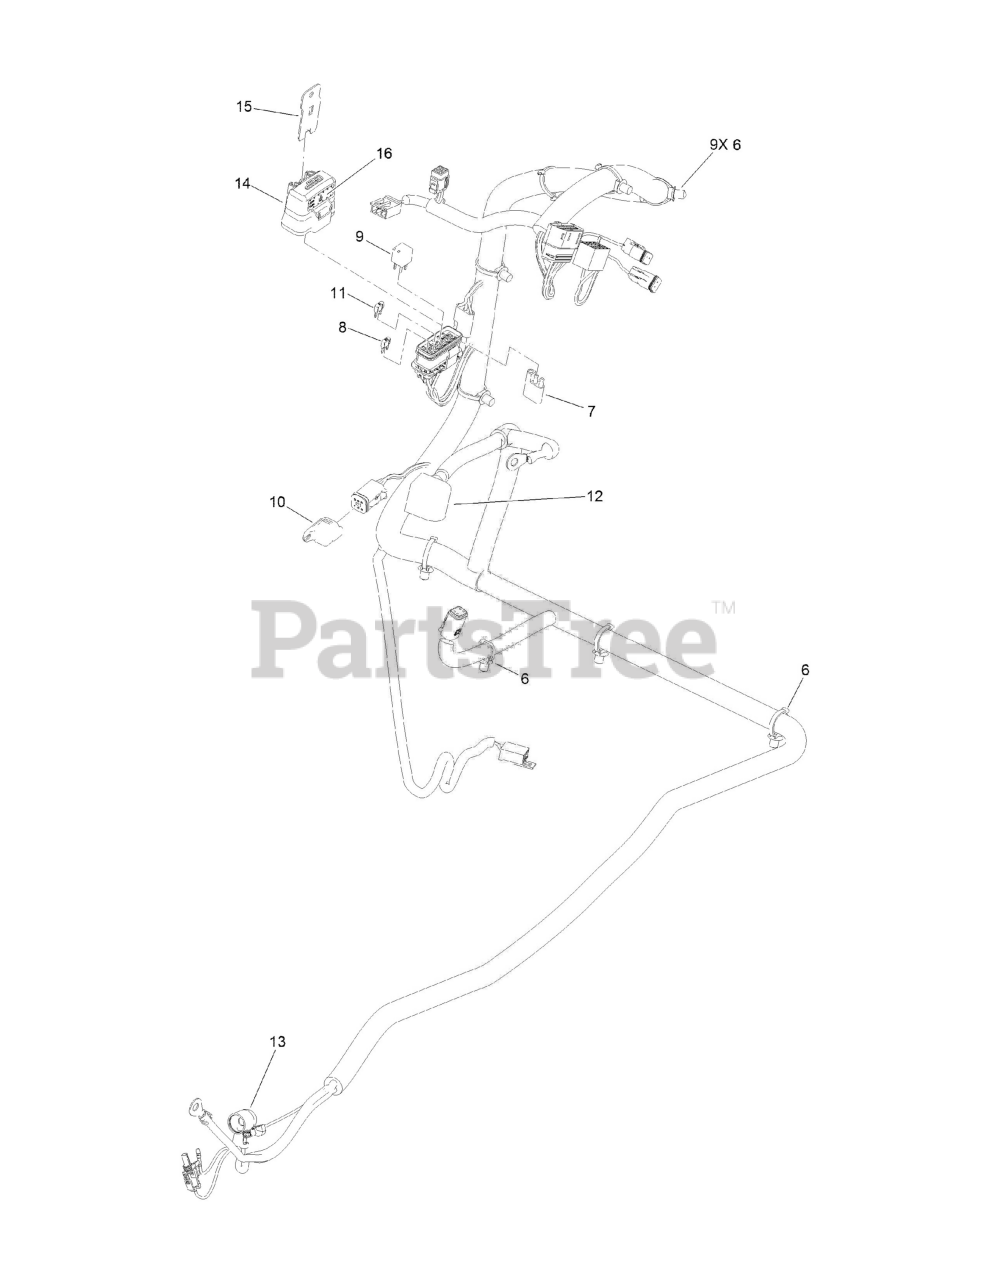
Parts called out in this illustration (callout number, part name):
6	CLIP-TIE
7	Cap-Plug
8	FUSE-MINI BLADE, 20 AMP
9	RELAY-MICRO
10	CAP-PLUG, 6 WAY
11	FUSE-MINI BLADE, 15 AMP
12	INSULATOR-BATTERY
13	INSULATOR-SOLENOID
14	COVER-BLOCK, FUSE
15	CLIP-MOUNTING
16	DECAL-FUSE
